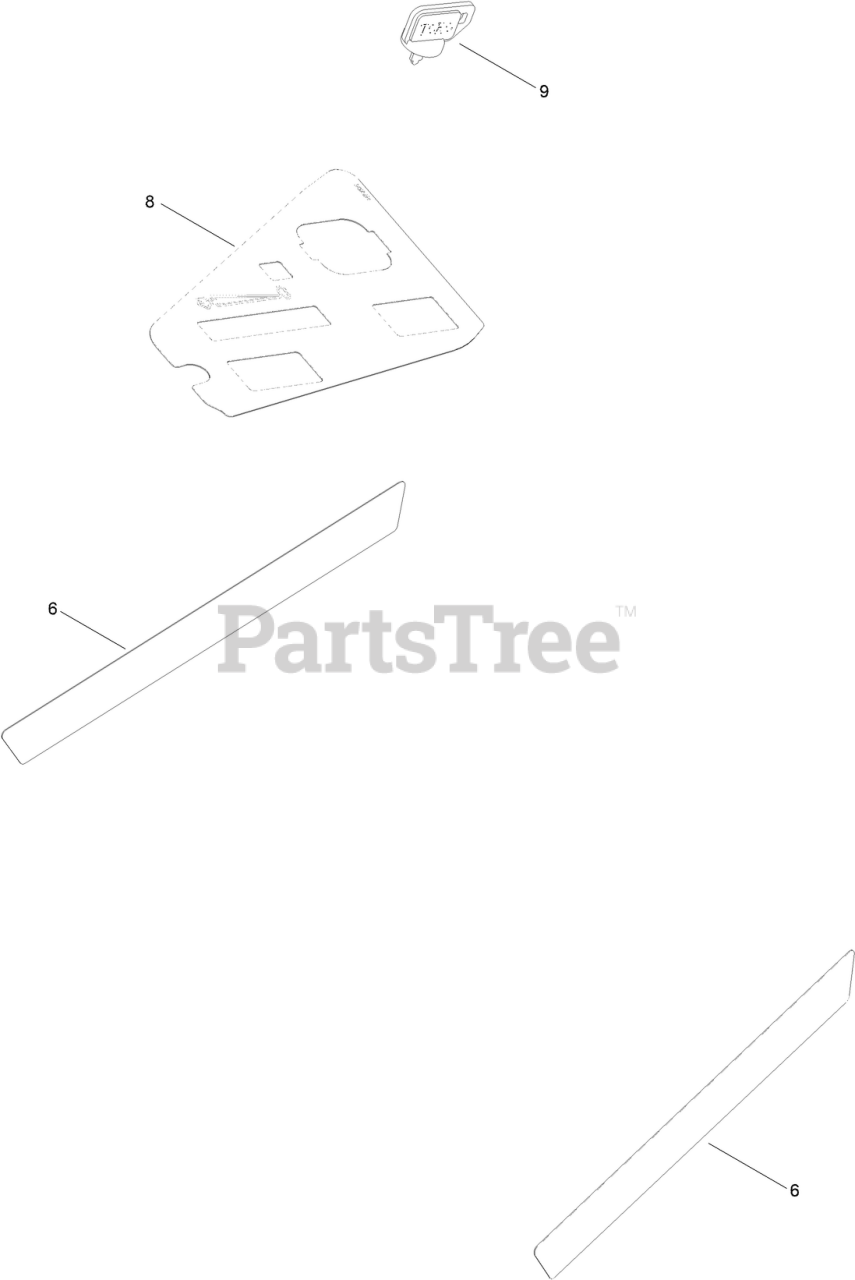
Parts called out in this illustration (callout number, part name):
6	DECAL - TIMECUTTER
8	DECAL - CONTROL PANEL
9	KEY-IGNITION
